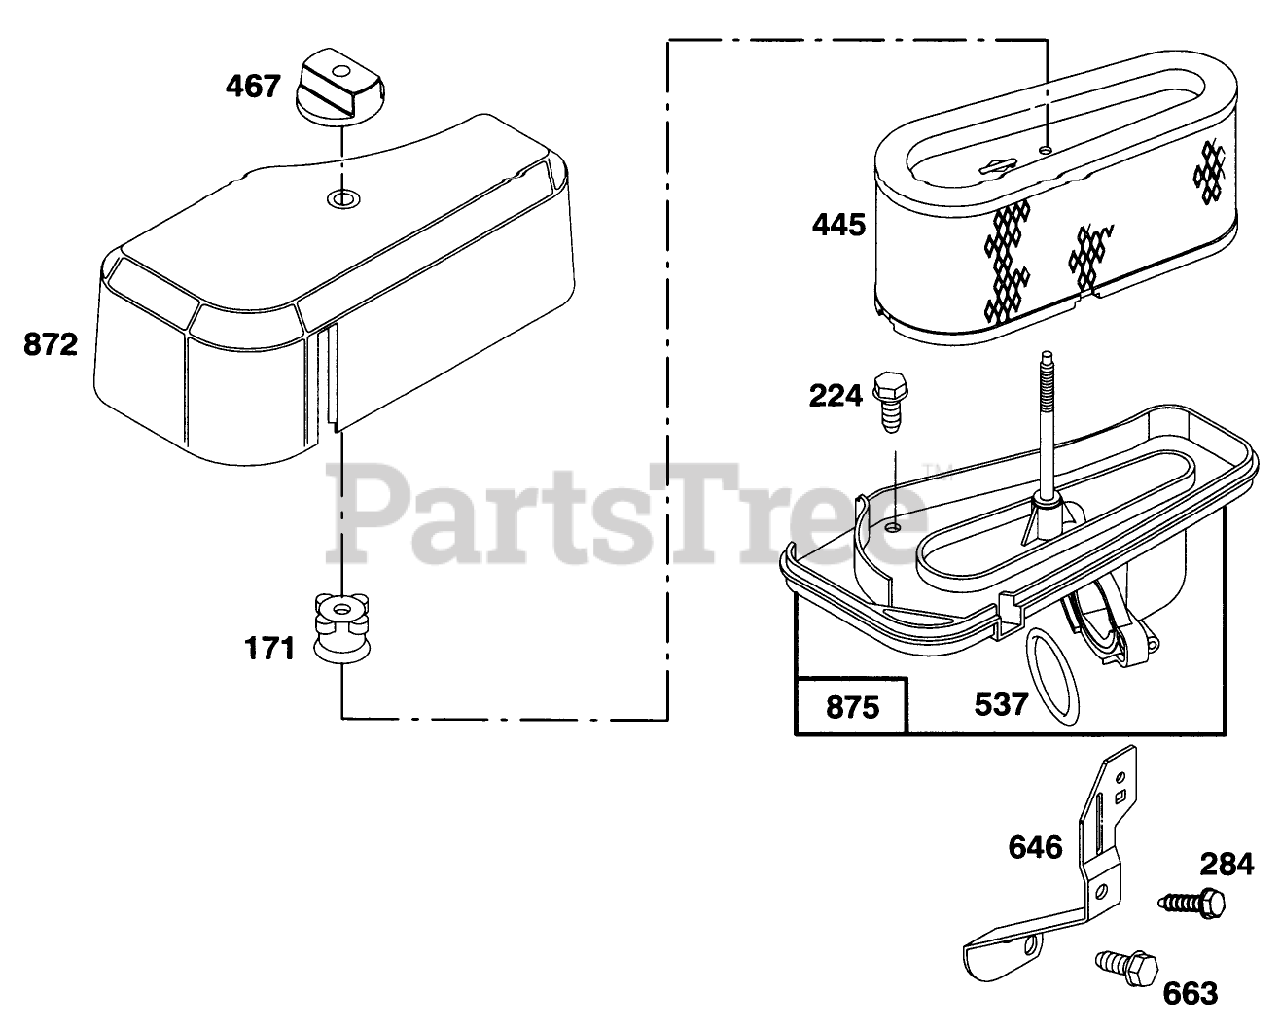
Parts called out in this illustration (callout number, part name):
224	Screw-Sem
284	Screw
445	Filter-Air
537	O-Ring
646	Brace-Air Cleaner
663	Screw
872	Cover-Air Cleaner
875	Base-Air Cleaner
